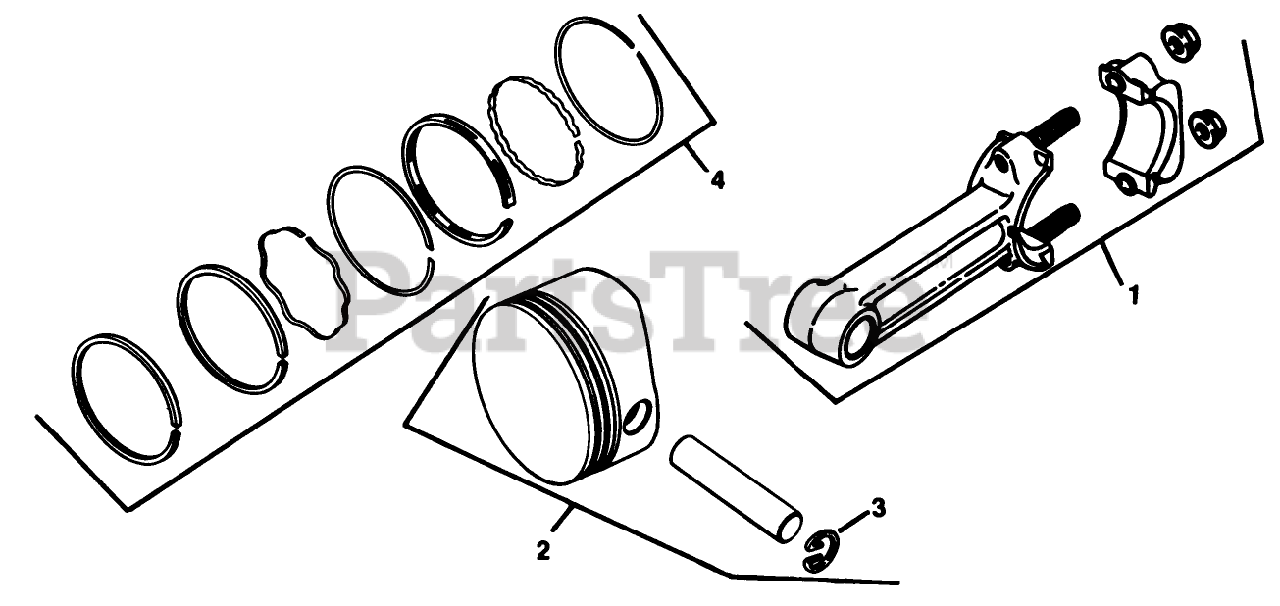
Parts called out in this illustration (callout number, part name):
1	Rod-Connecting Std.
1	Rod-Connecting .010"
2	Piston & Ring Set Std.
2	Piston & Ring Set .003"
2	Piston & Ring Set .010"
2	Piston & Ring Set .020"
2	Piston & Ring Set .030"
3	Retainer, Pin
4	Ring Set (Std. & .003)
4	Ring Set (.010)
4	Ring Set (.020)
4	Ring Set.030"
